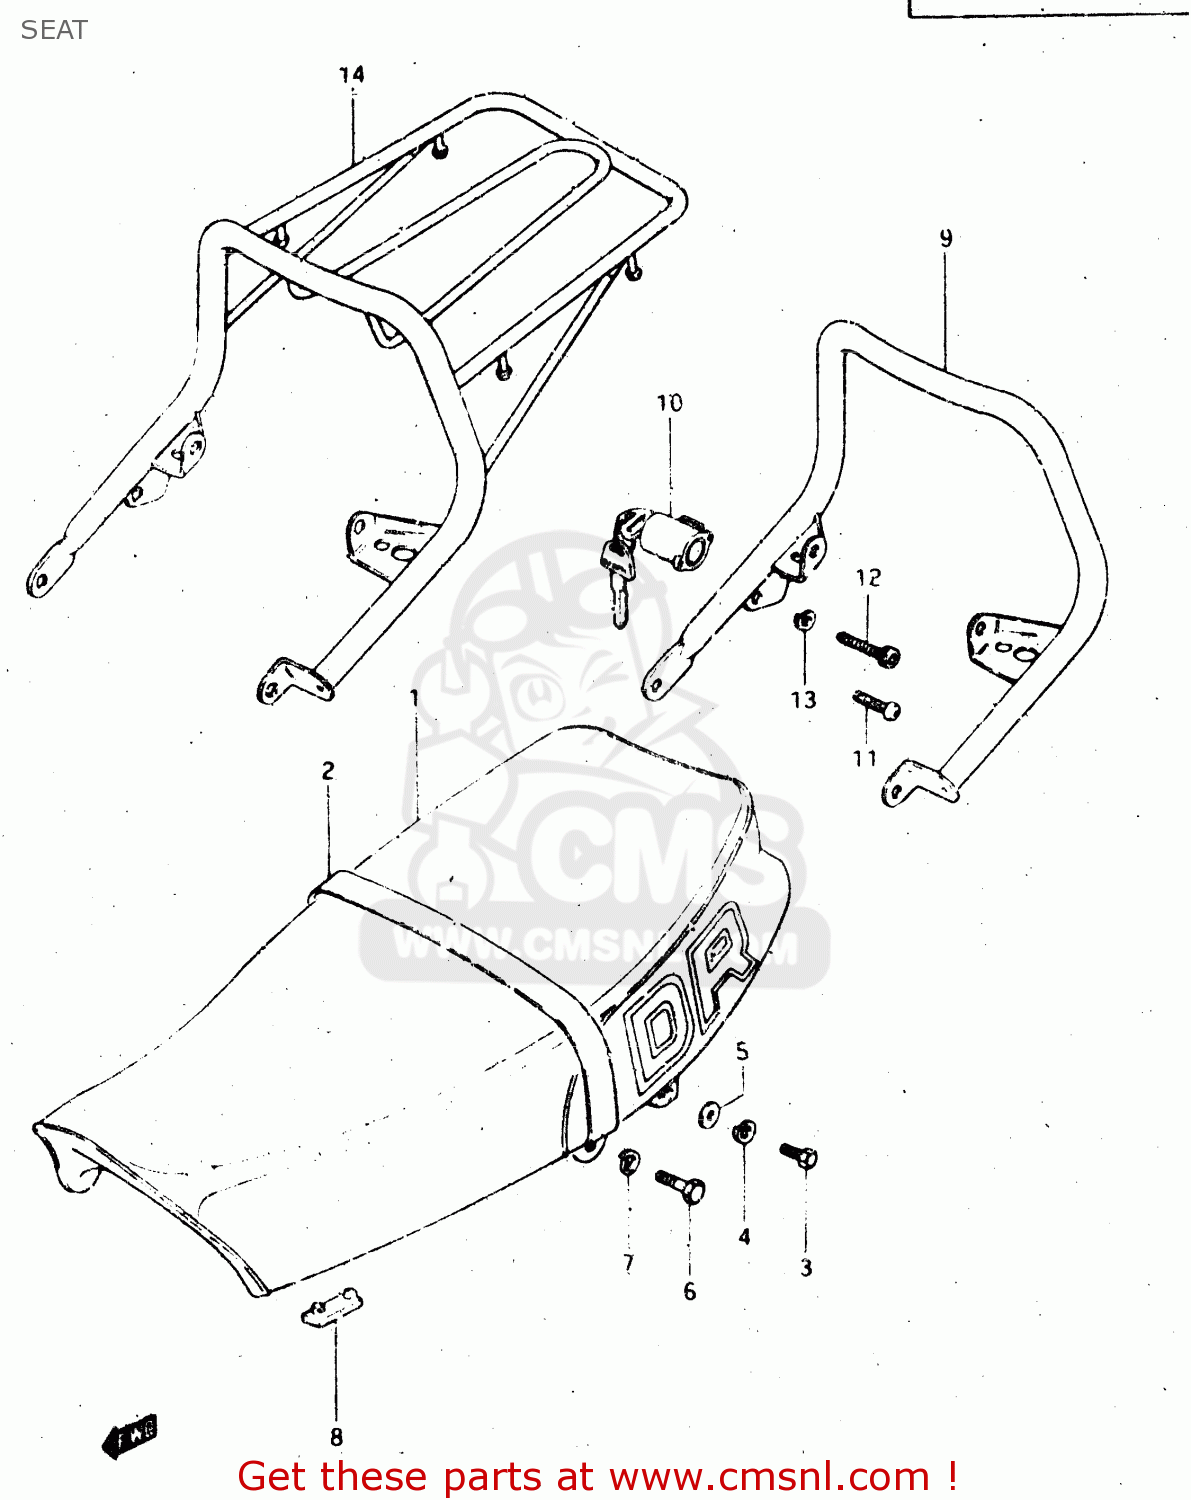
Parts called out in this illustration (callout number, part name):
1	SEAT ASSY (BLUE)
2	BAND,SEAT
3	BOLT
4	WASHER,LOCK,8.
5	WASHER
6	BOLT
7	LOCK WASHER
8	CUSHION
9	HANDLE, PILLION RIDER
10	LOCK SET,HELMET
11	SCREW
12	BOLT 6X11
13	LOCK WASHER
14	CARRIER, SPORTS
